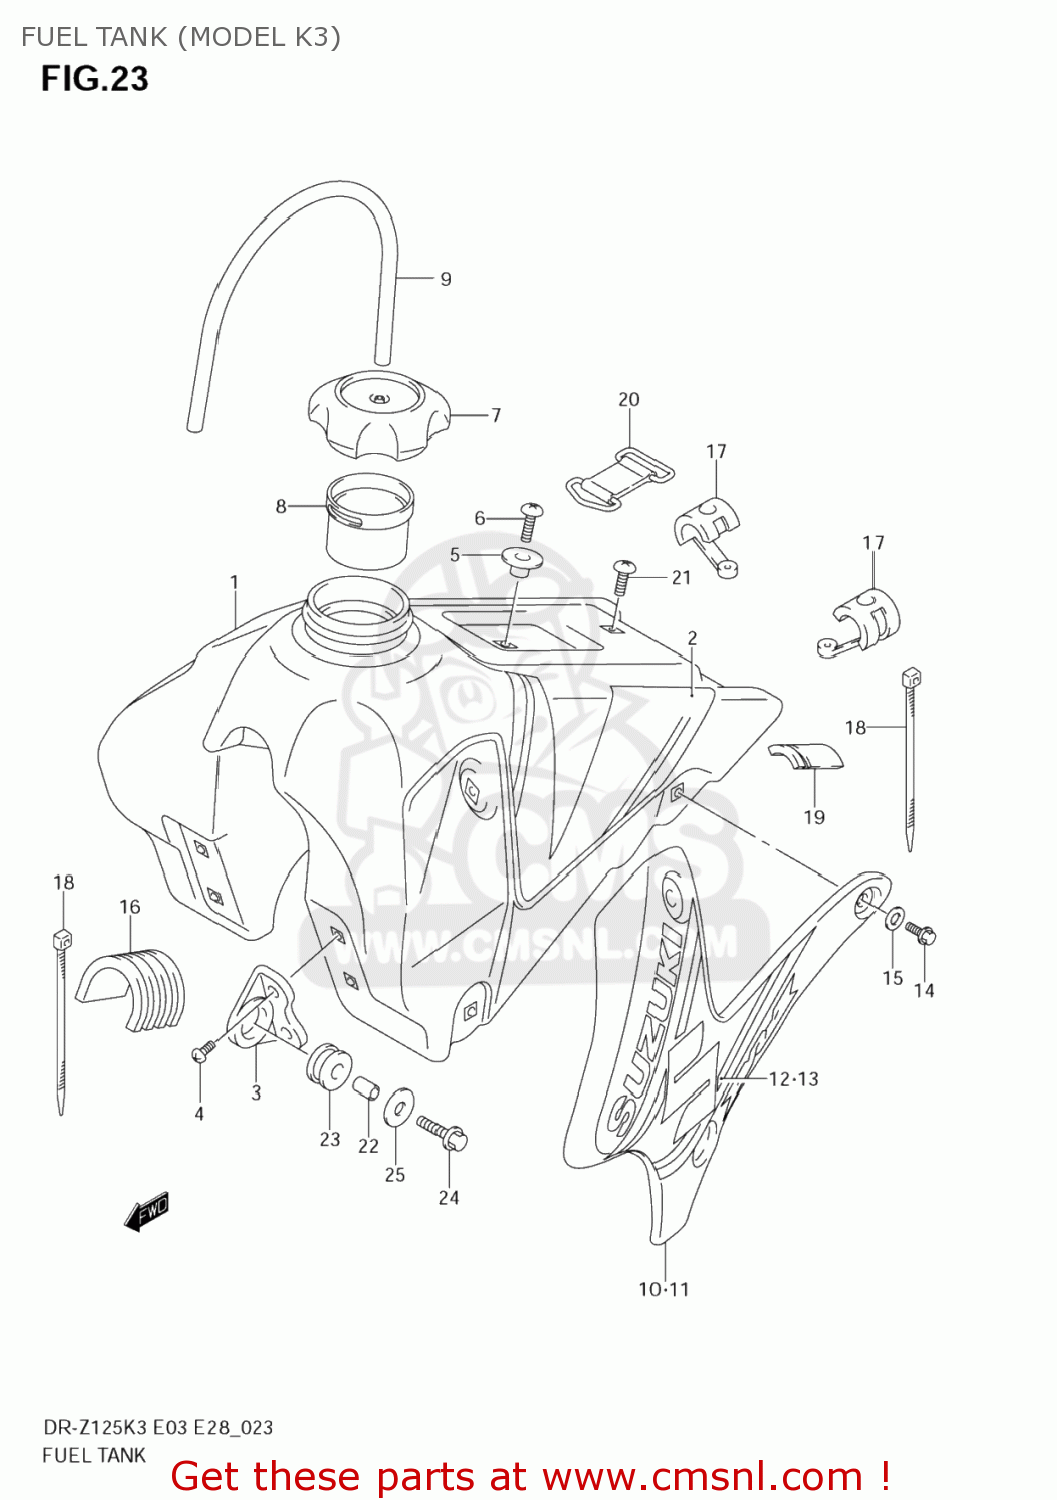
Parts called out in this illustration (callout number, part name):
1	TANK, FUEL (YELLOW)
2	TAPE SET,FUEL TANK
3	BRACKET,FUEL TANK FR
4	SCREW
5	HOOK,SEAT FR
6	SCREW
7	CAP ASSY,FUEL TANK FILLER
8	TUBE,FILLER INLET
9	HOSE(5X8.2X600)
10	COVER, TANK FRONT RH (YELLOW)
11	COVER, TANK FRONT LH (YELLOW)
12	TAPE,FUEL TANK COVER,R
13	TAPE,FUEL TANK COVER,L
14	BOLT
15	WASHER
16	CUSHION,FUEL TANK
17	CUSHION,FUEL TANK SIDE
18	CLAMP(L:300)
19	CUSHION,FUEL TANK RR
20	BAND,FUEL TANK RR
21	SCREW
22	SPACER(6.5X9X13.5)
23	CUSHION,FUEL TANK FR
24	SCREW
25	WASHER(6.5X24X1.2)
